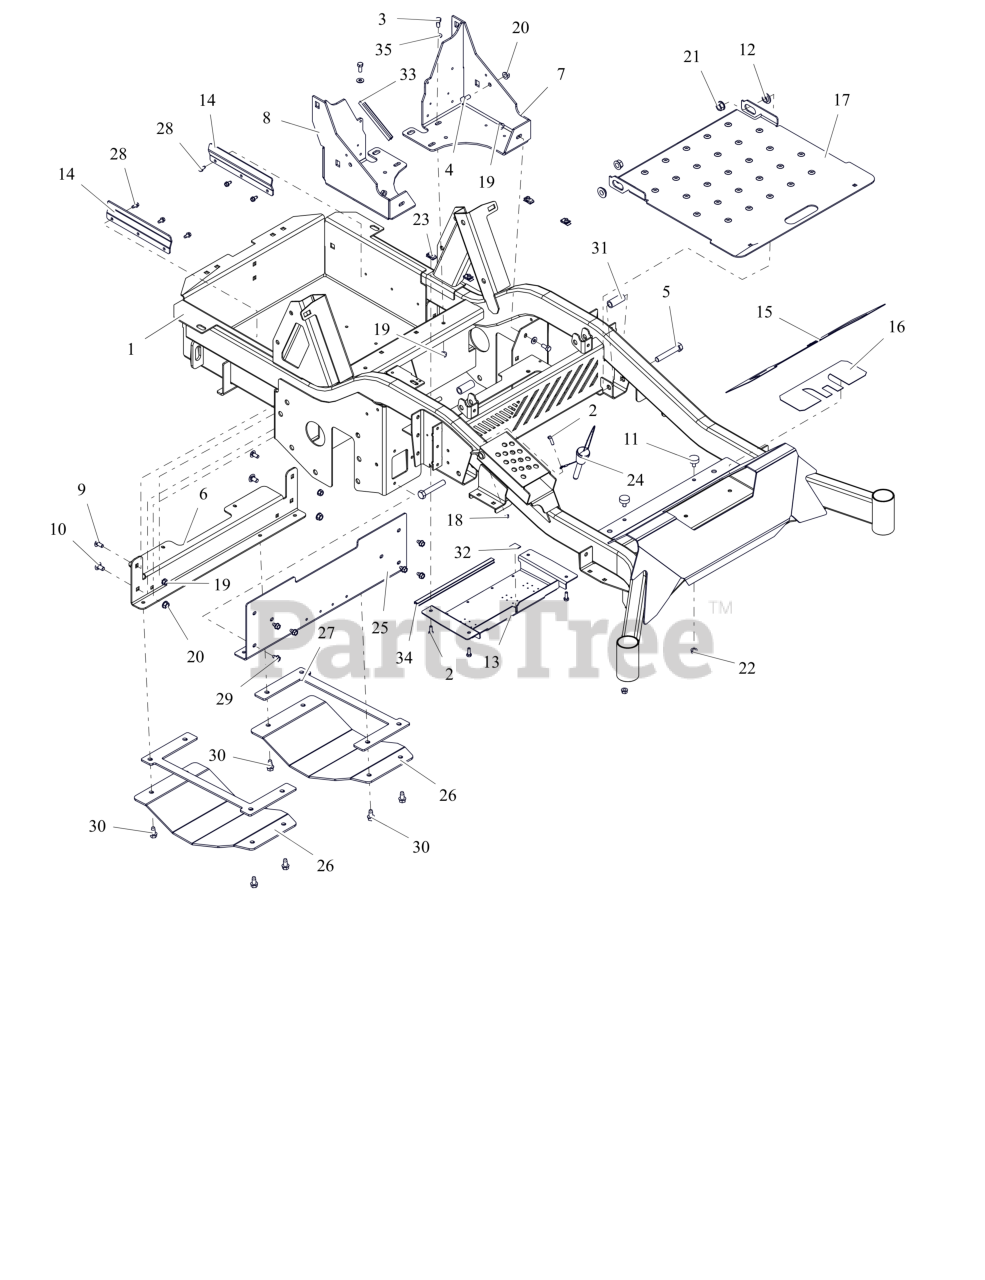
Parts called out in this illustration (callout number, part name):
1	WLDMT, MAIN FRAME PRO-TURN EV 60-A (ORANGE)
2	BLT, HEX .25-20X.75 G5 ZCC
3	BLT,HEX .31-18X.75 G5 ZCC
4	BLT,HEX .38-16X.75 G5 ZCC
5	BLT, HEX .50-13X3.00 G5 ZCC
6	BRKT, SKID PLATE MTG. (ORANGE)
7	BRKT, SUPPORT ROPS -LH (ORANGE)
8	BRKT, SUPPORT ROPS-RH (ORANGE)
9	BLT, RHSSN.31-18X.750 G5 ZCC
10	BLT, RHSSN .38-16X.75 G5 ZCC
11	BUMPER, RUBBER
12	BSHG-FLG .515X.750X.395X1.120
13	COVER, BOTTOM ACCESS -OPEN (ORANGE)
14	DEFLECTOR, BATTERY -EV (ORANGE)
15	GRIP, FRONT
16	GRIP, TAPE FRONT
17	PANEL, ACCESS
18	NUT-LK-CTR-FLG .25-20 ZC120
19	NUT,LK-CTR-FLG .31-18 GF ZCC
20	NUT-LK-CTR-FLG .375-16 GF ZCC
21	NUT-LK-CTR-FLG .500-13 GG ZCC
22	NUT,SPNLK-FLG .31-18 G5 ZCC
23	NUT-RTNR .25-20X.56
24	PIN, MAGNETIC .50X2.50
25	PLATE, FRONT FRAME (ORANGE)
26	PLATE, SKID (BLACK)
27	PLATE, SKID TENSION (BLACK)
28	SCR-TAP .25-20X.50 HWH ZCC
29	SCR,TAP .312-18X.50 HWH TR ZCC
30	SCR,TAP .375-16X.75 HWH TR ZCC
31	SPACER, .515X.75X1.83
33	STRIP, COWL
34	STRIP, COWL
35	WSHR, FLT .312X.734X.065 ZCC
